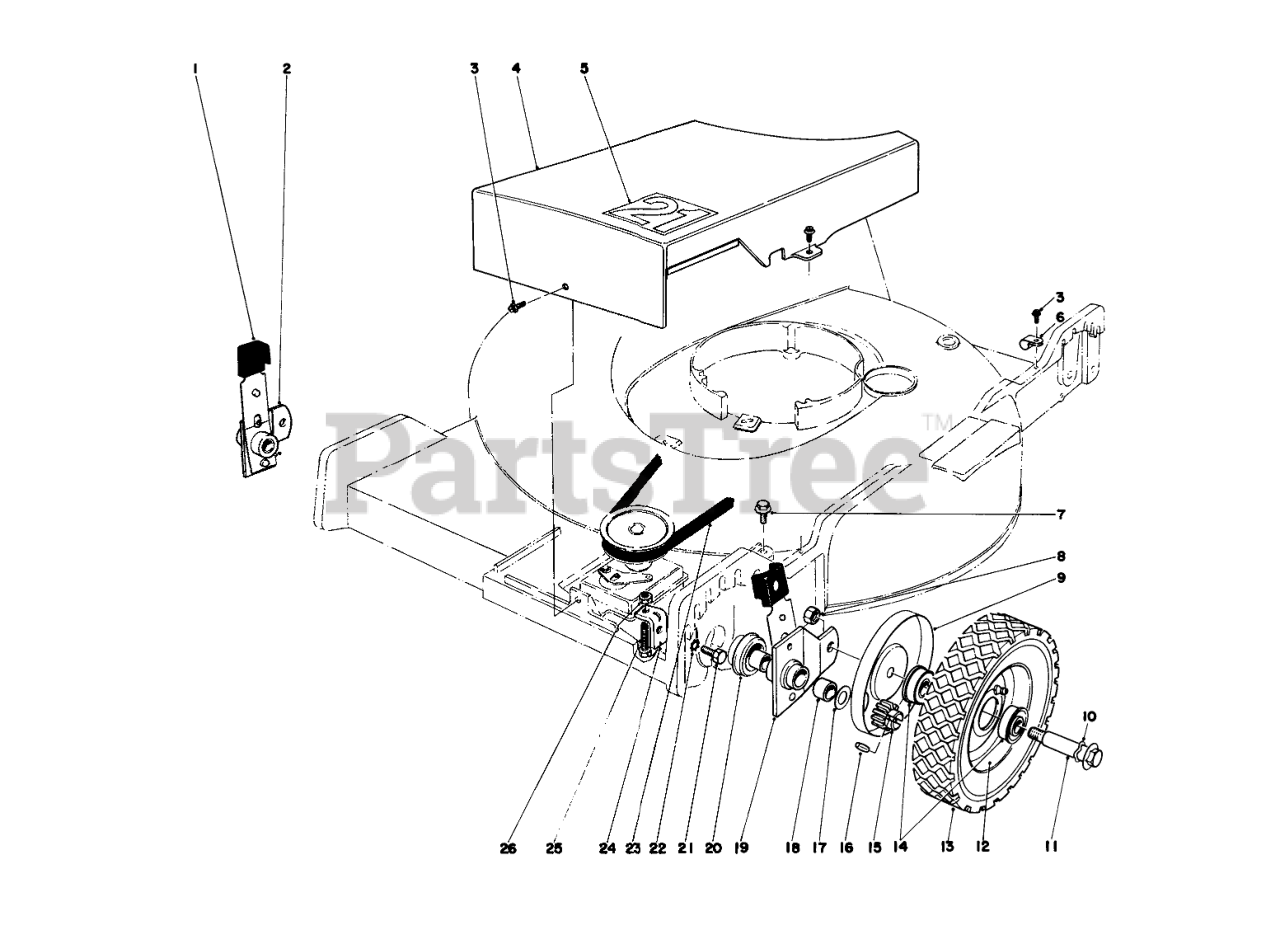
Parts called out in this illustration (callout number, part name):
1	KNOB-ARM
2	Pivot Arm (Incl. Ref. #18)
3	SCREW
4	Belt Cover
5	Decal-21"
6	CLAMP-NYLON
7	SCREW-HWHTF
8	Nut
9	WHEEL COVER
10	SPRING WASHER
11	WHEEL BOLT
12	Wheel & Tire Assembly (Incl. Ref. #13 & 14)
14	BEARING-BALL
15	Pinion
16	PIN-GROOVED
17	WASHER-THRUST
18	BUSHING
19	Pivot Arm (Incl. Ref. #18)
20	End Cap
21	SCREW-HH
22	WASHER-LOCK
23	V-BELT
24	Bracket-Gear Box
25	SCREW
26	NUT-LOCK
